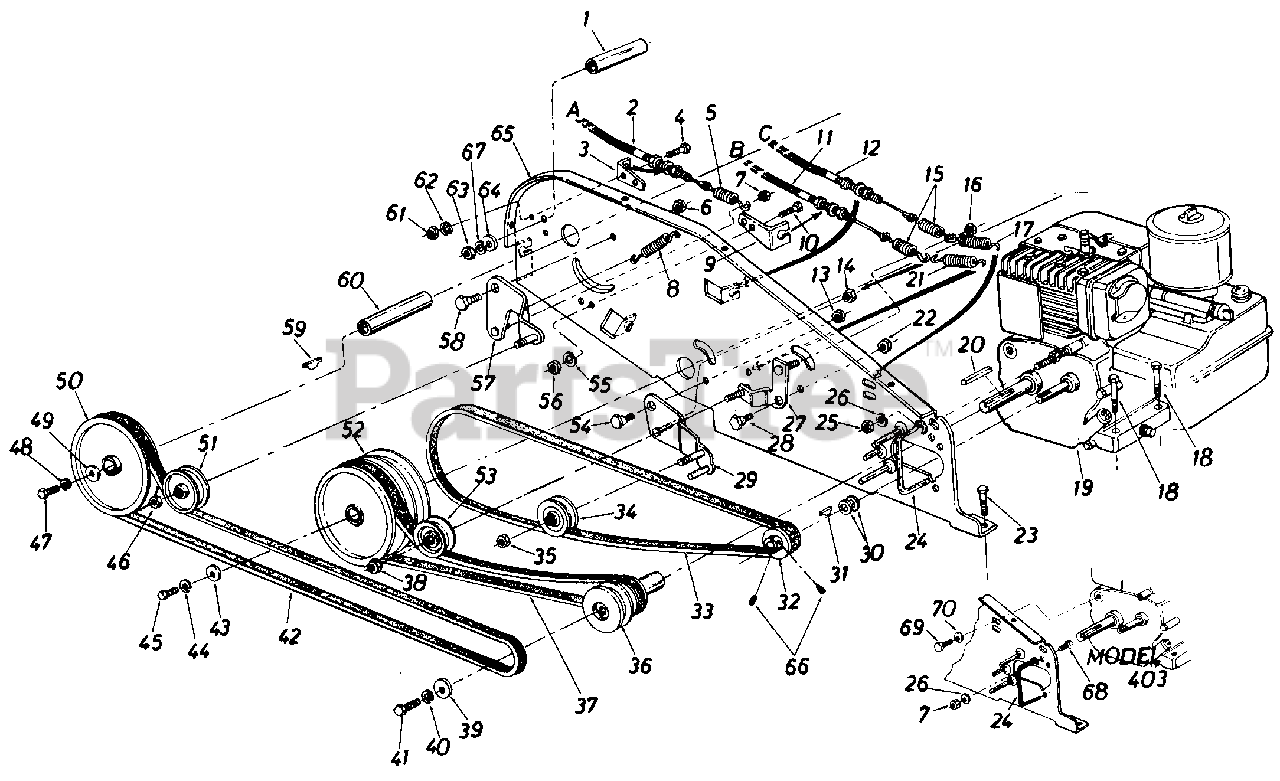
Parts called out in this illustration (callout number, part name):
1	Spacer.375" I.D. x .500" O.D. x 2.00" Lg.
2	Clutch Control Cable
3	Clutch Cable Bracket
4	Hex Bolt 5/16-18 x .75" Lg.
5	Extension Spring .50" O.D. x 2.50" Lg.
6	Hex Cent. L-Nut 3/8-16 Thd.
7	Hex Nut 1/4-20 Thd.
8	Extension Spring .50" O.D. x 1.55" Lg.
9	Clutch Cable Bracket
10	Hex Bolt 5/16-18 x .75" Lg.
11	Clutch Control Cable 42" Lg.
12	Clutch Control Cable 41" Lg.
13	Hex Cent. L-Nut 3/8-16 Thd.
14	Hex Cent. L-Nut 1/4-20 Thd.
15	Springs
16	Hex Cent. L-Nut 1/4-20 Thd.
17	Extension Spring .41" O.D. x 2.05" Lg.
18	Hex Bolt 5/16-18 x 1.50" Lg
19	Engine
20	Sq. Key 3/16 x 1.00" Lg.
21	Extension Spring .50" O.D. x 2.75" Lg.
22	Hex Cent. L-Nut 3/8-16 Thd.
23	Hex Bolt 5/16-18 x .75" Lg.
24	Belt Keeper
25	Hex Nut 1/4-20 Thd.
26	Bell-Wash. .265" I.D. x .75" O.D.
31	#5 Hi-Pro-Key 1/8" x 5/8" Dia.
32	1/2" V-Pulley 2.25" O.D. x .503" I.D.
33	"V"-Belt 1/2" x 43.0" Lg.
34	"V"-Belt Idler 2.62" O.D.
35	Hex Ins. L-Nut 3/8-24 Thd.
36	1/2" "V"-Pulley Ass'y.
37	"V"-Belt 1/2" x 39.0" Lg.
38	Hex Ins. L-Nut 3/8-24 Thd.
39	Fl-Wash. .344" I.D. x 1.125" O.D.
40	L-Wash. 5/16" I.D.
41	Hex Bolt 5/16-24 x 1.00" Lg.
42	"V"-Belt 1/2 x 54.0" Lg.
43	Fl-Wash. 1/4" I.D. x .93' O.D.
44	L-Wash. 1/4" I.D.
45	Hex Bolt 1/4-28 x .75n Lg.
46	Hex Ins. L-Nut 3/8-24 Thd.
47	Hex Bolt 1/4-28 x .75' Lg.
48	L-Wash. 1/4" I.D.
49	Fl-Wash. 1/4" I.D. x .93" O.D.
50	Fl-Pulley w/Flanges 6.0" O.D.
51	Fl-Idler w/Flanges 3.75" O.D.
52	Double Fl-Pulley 5/8" I.D. x 6.0" O.D.
53	Fl-Idler with Flanges 2.12" O.D.
54	Shld. Bolt .500" Dia. x .170" Lg.
55	L-Wash. 5/16" I.D.
56	Hex Nut 5/16-18 Thd.
59	#61 Hi-Pro-Key 3116" x 518" Dia.
60	Spacer .647" I.D. x 2.75" Lg.
61	Hex Nut 5/16-18 Thd.*
62	L-Wash. 5/16 I.D.
63	Hex Nut 5/16-18 Thd.
64	Fl-Wash. .406" I.D. x .750" O.D.
65	Side Plate Ass'y.
66	Set Scr. 1/4-28 x .251' Lg.
67	L-Wash. 5/16" I.D.
68	Hex Bolt 1/4-20 x 1.25" Lg.
69	Hex Bolt 5/16-24 x .62" Lg.
70	Bell-Wash. 5/16" I.D.
